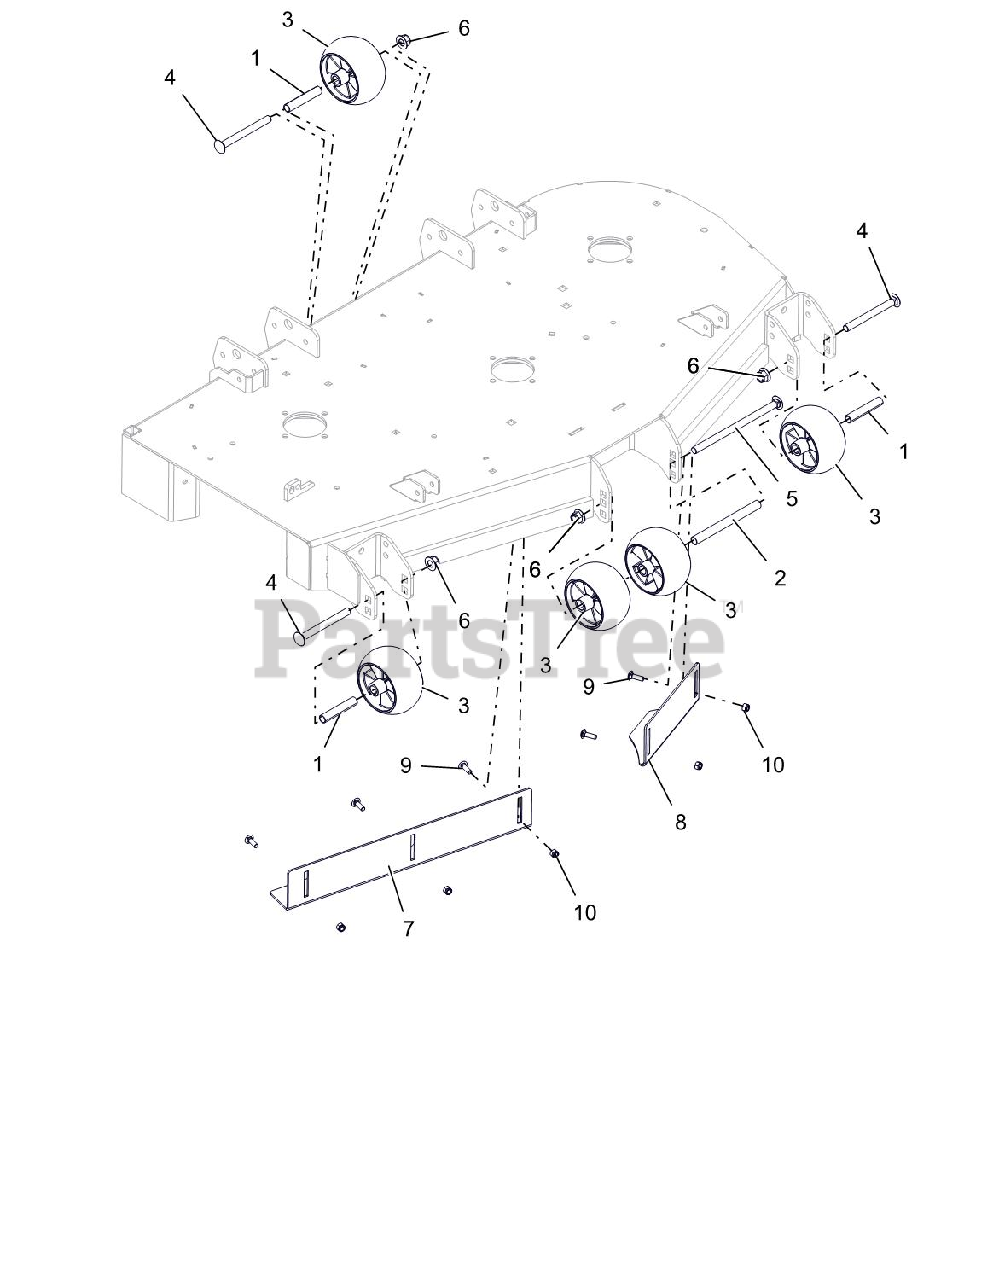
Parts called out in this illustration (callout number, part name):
1	SPACER, .510X.625X3.35
2	SPACER, .510 X .625 X 6.50
3	ANTI-SCALP WHEEL
4	BOLT, CARRIAGE 0.5-13X5 GR5
5	BOLT, CARRIAGE 0.5-13X8.5 GR5
6	NUT-LK-NYL-FLG .50-13 YWZC
7	BAFFLE, 48" RH VACUUM
8	BAFFLE, 44/48" LH VACUUM
9	BOLT, CARRIAGE 0.3125-18X1 GR5
10	NUT-LK-NYL .312-18 YWZC
